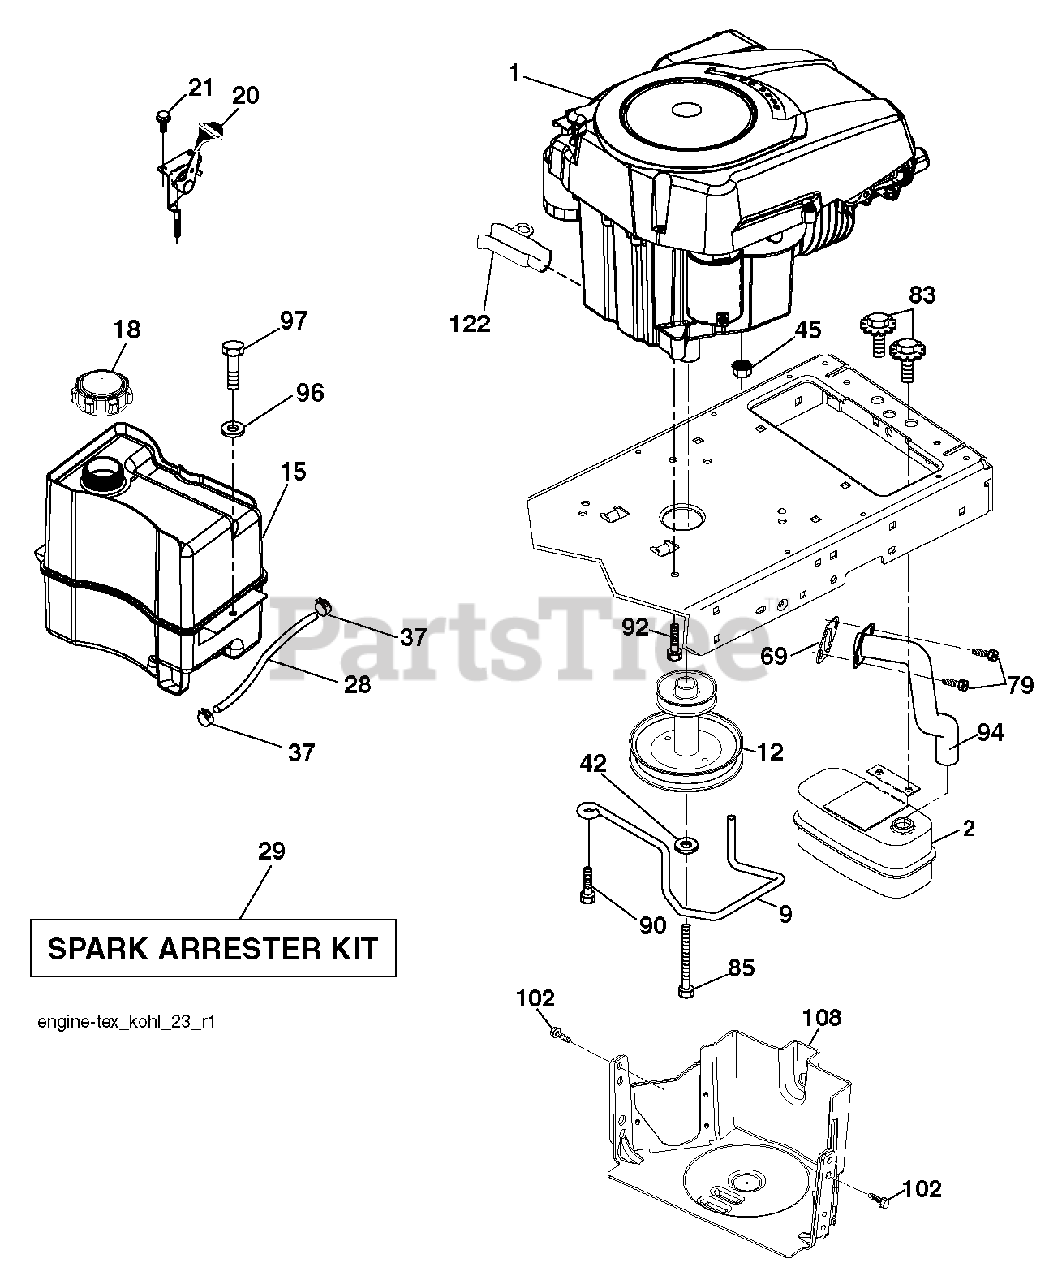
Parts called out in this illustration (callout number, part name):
2	MUFFLER.SINGLE.CYL.KOHL/B&S
9	KEEPER.BELT.ENGINE.4.2
12	PULLY ENGINE
15	RP TANK FUEL FRT 1.5 GAL
18	CAP ASM.FUEL.2.25"FR.
20	CONTROL.TH/CK.C.
21	SCREW.#10 X 0.750.BOS
28	LINE.FUEL.20
29	KIT.SPARK ARRESTOR 794945 B&S
37	HOSE CLAMP
42	LOCKWASHER
45	NUT
69	GASKET.EXHAUST.KOHLER
79	SCREW.SOCKET HD.5/16-1
83	BOLT, 5/16-18 X 1 3/4
85	BOLT HEX 7/16-20X4-1/4"
90	SCREW 3/8-16X1
92	SCREW 3/8-16X1
94	RP.TUBE.EXHAUST.KOHL.COURAGE
97	SCREW HEXWSHR 1/4-20X3/4
102	SCREW 5/16-18X1
108	COVER PULLEY
122	EXTENSION DRAIN OIL
